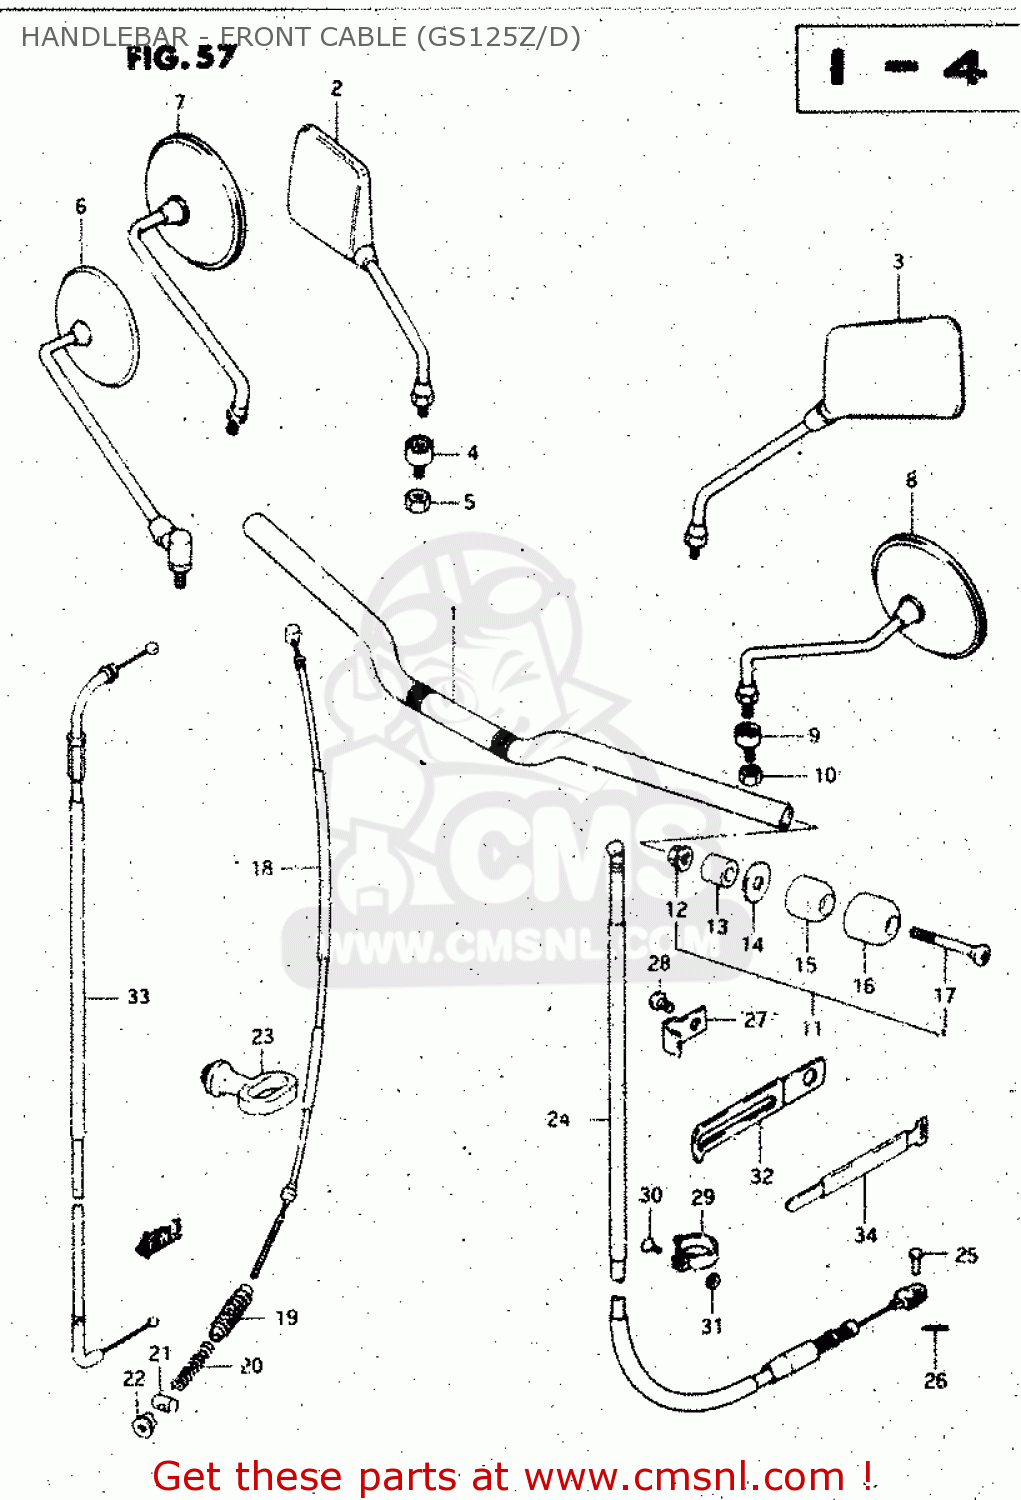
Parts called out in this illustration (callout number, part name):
1	HANDLEBAR
2	MIRROR ASSY, REAR VIEW RH
3	MIRROR ASSY, REAR VIEW LH
4	CUSHION ASSY,RR VIEW MIRROR
5	NUT
6	MIRROR ASSY,RR VIEW
7	MIRROR ASSY, REAR VIEW RH
8	MIRROR ASSY, REAR VIEW LH
9	CUSHION,REAR VIEW MIRROR
10	NUT
11	BALANCER SET,HANDLEBAR
12	NUT
13	EXPANDER,HANDLE BALANCER
14	SPACER,BALANCER
15	BALANCER,HANDLE
16	CAP,BALANCER
17	SCREW 6X65
18	CABLE,FR BRAKE
19	SEAL,DUST(7X16X75)
20	SPRING
21	PIN,10X19
22	NUT
23	GUIDE,CABLE
24	CABLE ASSY,CLUTCH
25	PIN(L:15)
26	PIN
27	CLAMP,CLUTCH CABLE NO.1
28	SCREW
29	CLAMP,CABLE
30	SCREW
31	NUT 5MM
32	CLAMP
33	CABLE ASSY,THROTTLE
34	CLAMP
